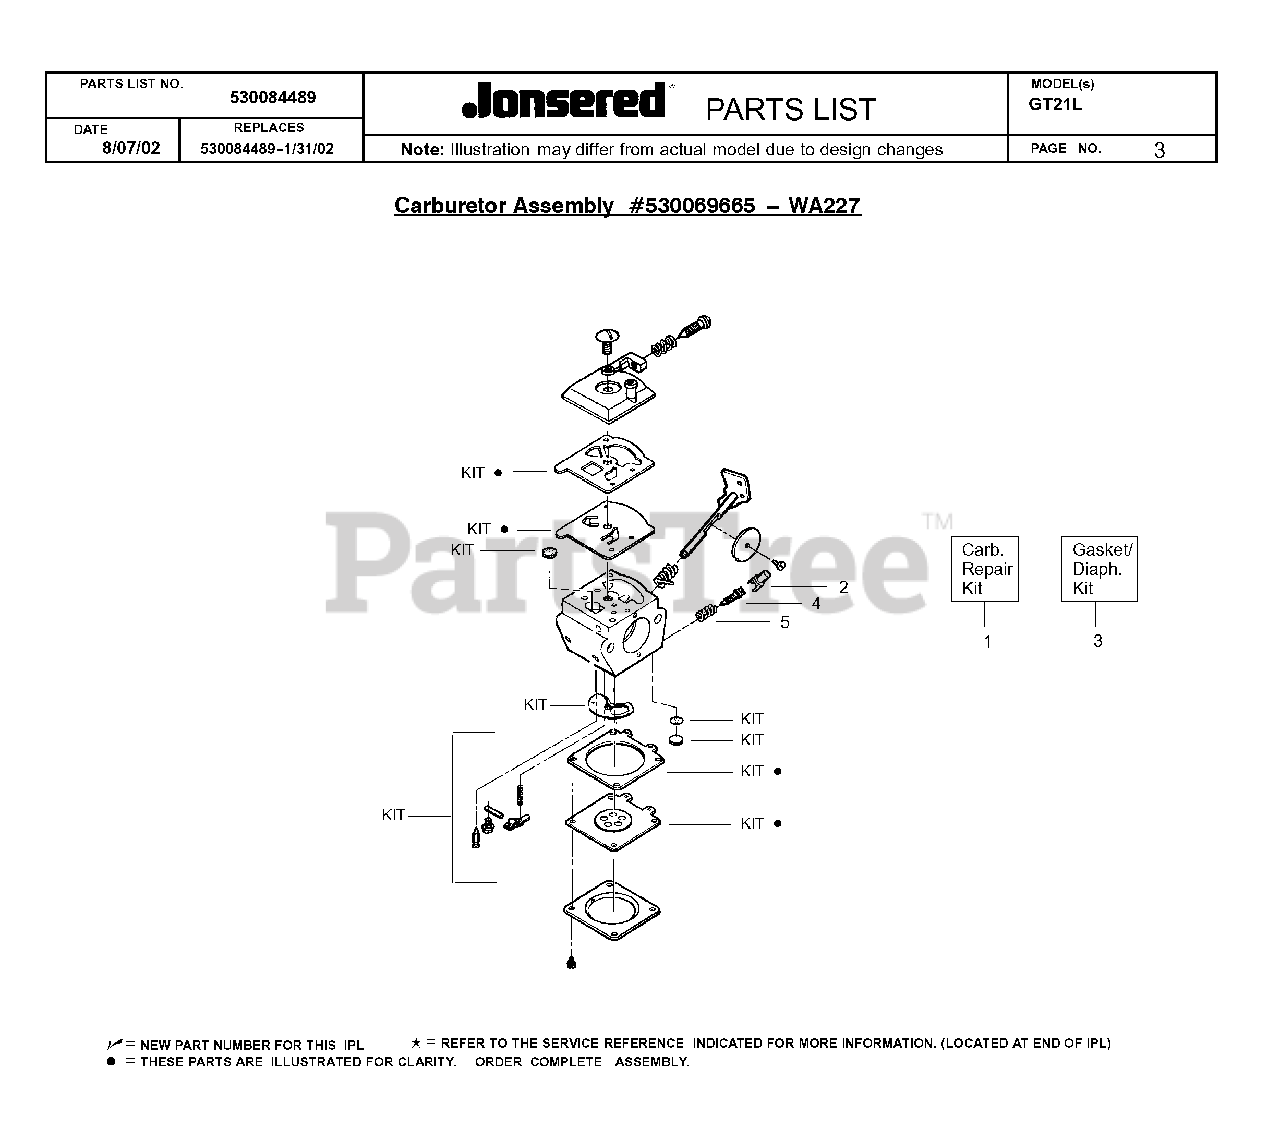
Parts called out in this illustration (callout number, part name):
2	LIMITER CAP
3	GASKET/DIAPHRAGM KIT
4	MIXTURE NEEDLE
